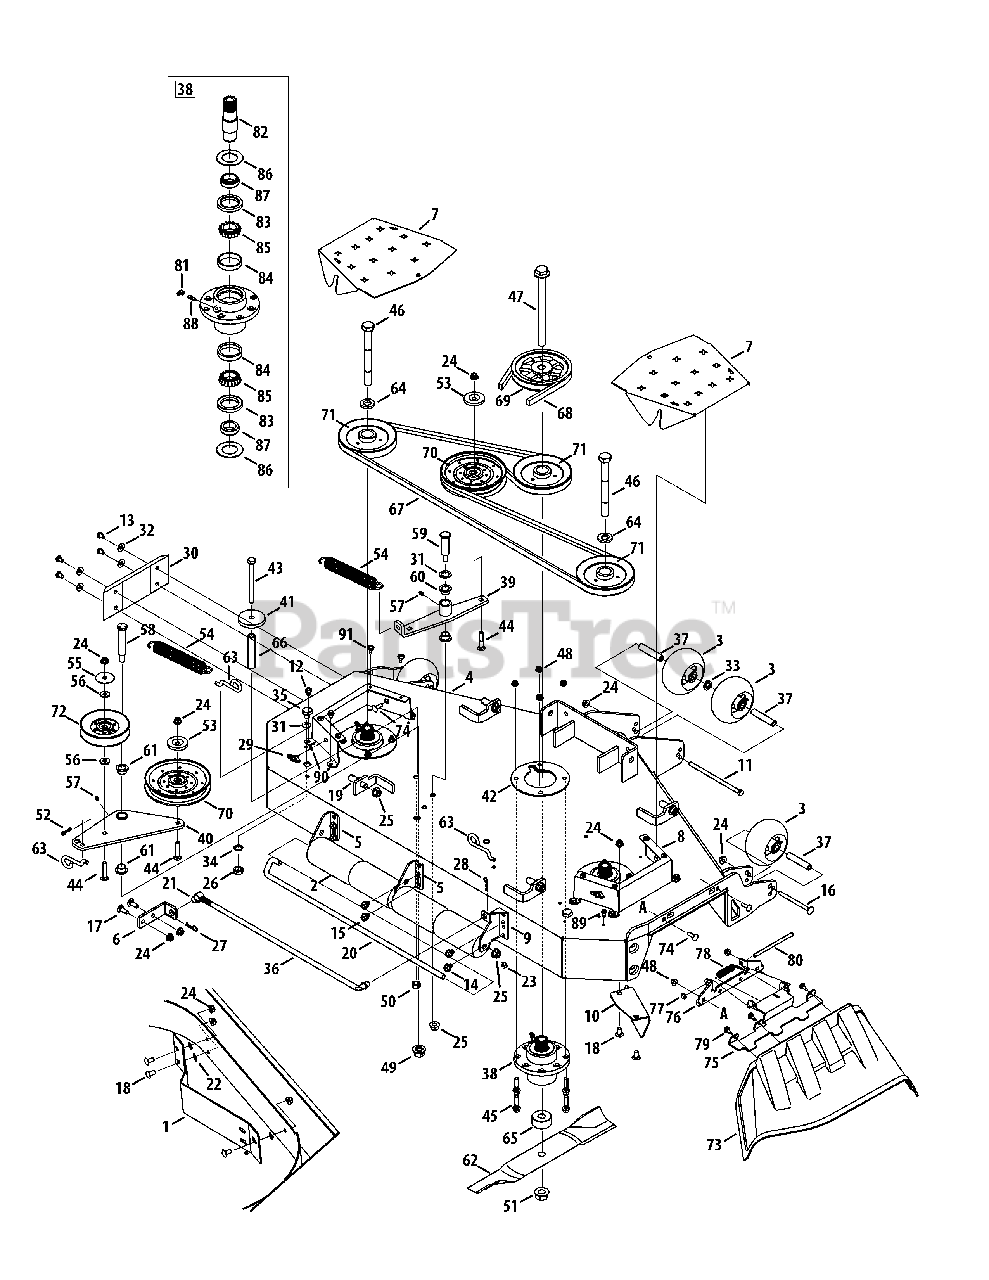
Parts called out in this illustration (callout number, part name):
1	Baffle, 54" Adjustment
2	Anti-Scalp Roller Assembly
3	Complete Wheel, 5.00 Dia.
4	54" Deck
5	Rear Roller Mount Bracket
6	Deck Stabilizer Mount Bracket
7	Deck Belt Cover
8	Deck Belt Cover Bracket
9	Rear Roller Bracket, RH
10	Chute Baffle
11	Hex Cap Screw, 3/8-16 x 7.25
12	Screw, 5/16-18 x .500
13	Screw, 5/16-18 x .500
14	Screw, 3/8-16 x .750
15	Screw, 3/8-16 x .500
16	Carriage Screw, 3/8-16 x 4.50
17	Carriage Bolt, 3/8-16 x 1.00
18	Carriage Bolt, 3/8-16 x .750
19	Pin, 1/2-13 x .625 x 1.2
20	J-Hook w/ Threaded Roller
22	Push Nut, 3/8
23	Jam Lock Nut, 3/8-16
24	Nut, 3/8-16, Flangelock
25	Nut, 1/2-13, Flangelock
26	Hex Nut, M16-1.5
27	Click Pin, .092 x 1.64
28	Internal Cotter Pin
30	Skid Guard Plate
31	Washer, .793 x 1.24 x .06
32	Flat Washer, .343 x .880 x .062
33	Flat Washer, .632 x 1.00 x .160
34	Lock Washer, 17 x 23.8 x 1.95
35	Plug, Screw, M16-1.5
36	Deck Support Rod, 1/2" Dia.
37	Wheel Spacer
38	Spindle Assembly
39	Deck Idler Arm
40	Idler Assembly
41	Spacer, .5375 x 2.75 x .375
42	Spindle Support Plate
43	Hex Cap Screw, 1/2-13 x 5.00
44	Screw, 3/8-16 x 2.00
45	Bolt, 5/16-18 x 1.25
46	Hex Cap Screw, 3/4-16 x 7.00
47	Hex Cap Screw, 3/4-16 x 9.00
48	Nut, 5/16-18, Flangelock
49	Nut, 5/8-18, Flangelock
50	Nut, 1/2-13, Hexlock
51	Nut, 3/4-16, Flangelock
52	Bow Tie Cotter Pin
53	Pulley Cap
54	Extension Spring, 1.248 x 8.5
55	Washer, .406 x 1.92 x .060
56	Washer, .406 x 1.00 x .105
57	Grease Fitting
58	Shoulder Bolt, 1.0 x 3.15, 5/8-18
59	Shoulder Bolt, .750 x 2.23, 1/2-13
60	Flange Bearing, .75 x .52
61	Flange Bearing, 1.00 x .75
62	Hi-Lift Blade, 19.0
63	Spring Rod Hook
64	Spacer, .812 x .218
65	Spacer, .760 x 2.00 x .925
66	Spacer, .405 x .75 x 3.875
69	Pulley, 6.96 OD x .750 ID
70	Idler Pulley
71	Spindle Pulley
72	Idler Pulley
73	Discharge Chute Assembly
74	Carriage Bolt, 5/16-18 x 1.00
77	Push Cap
78	Torsion Spring
79	Shoulder Screw, 1/4-20
80	Chute Rod
81	Grease Fitting, 45 degree, 1/4-28
82	Spindle Shaft
83	Seal, Oil
84	Cup Bearing
85	Cone Bearing
86	Washer, 1.50 x 2.52 x .075
87	Ring, Seal
88	Straight Adapter Fitting
89	Hex Flange Screw, 1/4-20 x .500
90	Speed Nut, .3125
91	Bumper, .62 Dia. x .3
